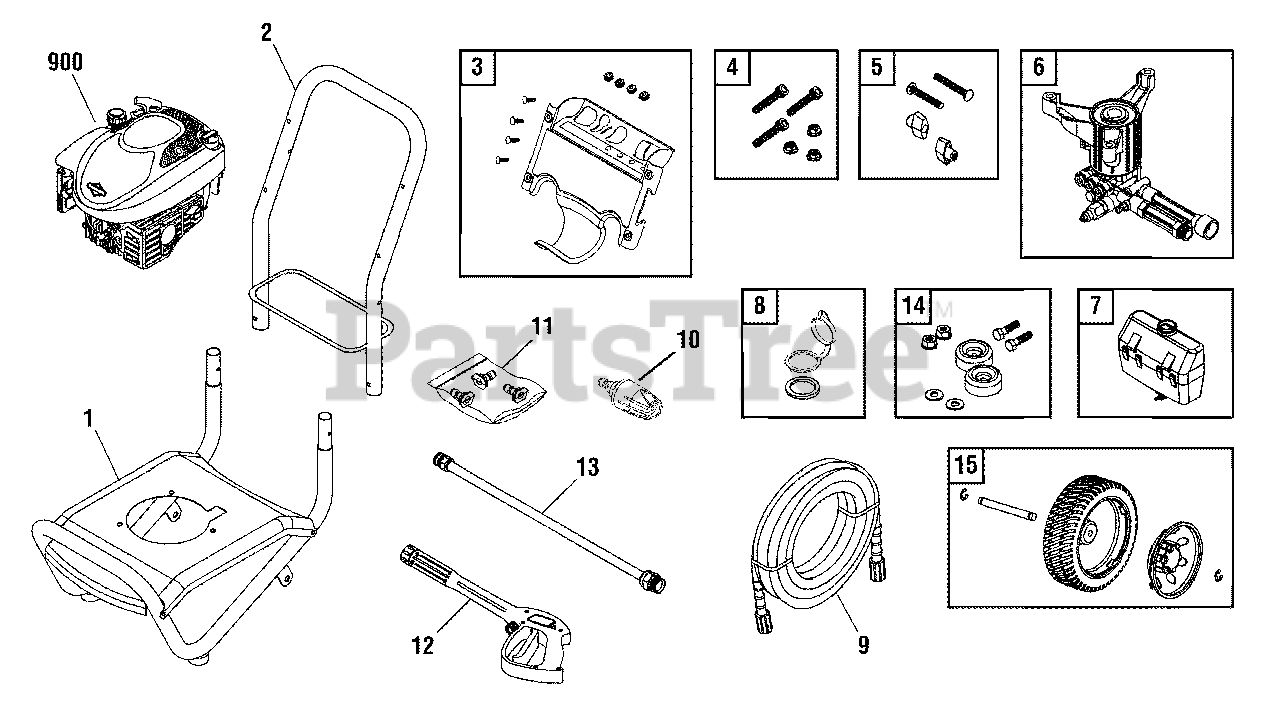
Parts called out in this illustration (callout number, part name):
2	ASSY, Handle/Wireform
3	KIT, Billboard Assy, w/Decals & Clips
4	KIT, Pump Mounting Hardware
5	KIT, Handle Connector
6	PUMP
7	ASSY, Chem Tank
8	KIT, Cap, Chem Container
10	ASSY, Turbo Max
11	KIT, Nozzle
12	GUN
13	EXTENSION
14	KIT, Vibration Mount
900	* ENGINE
